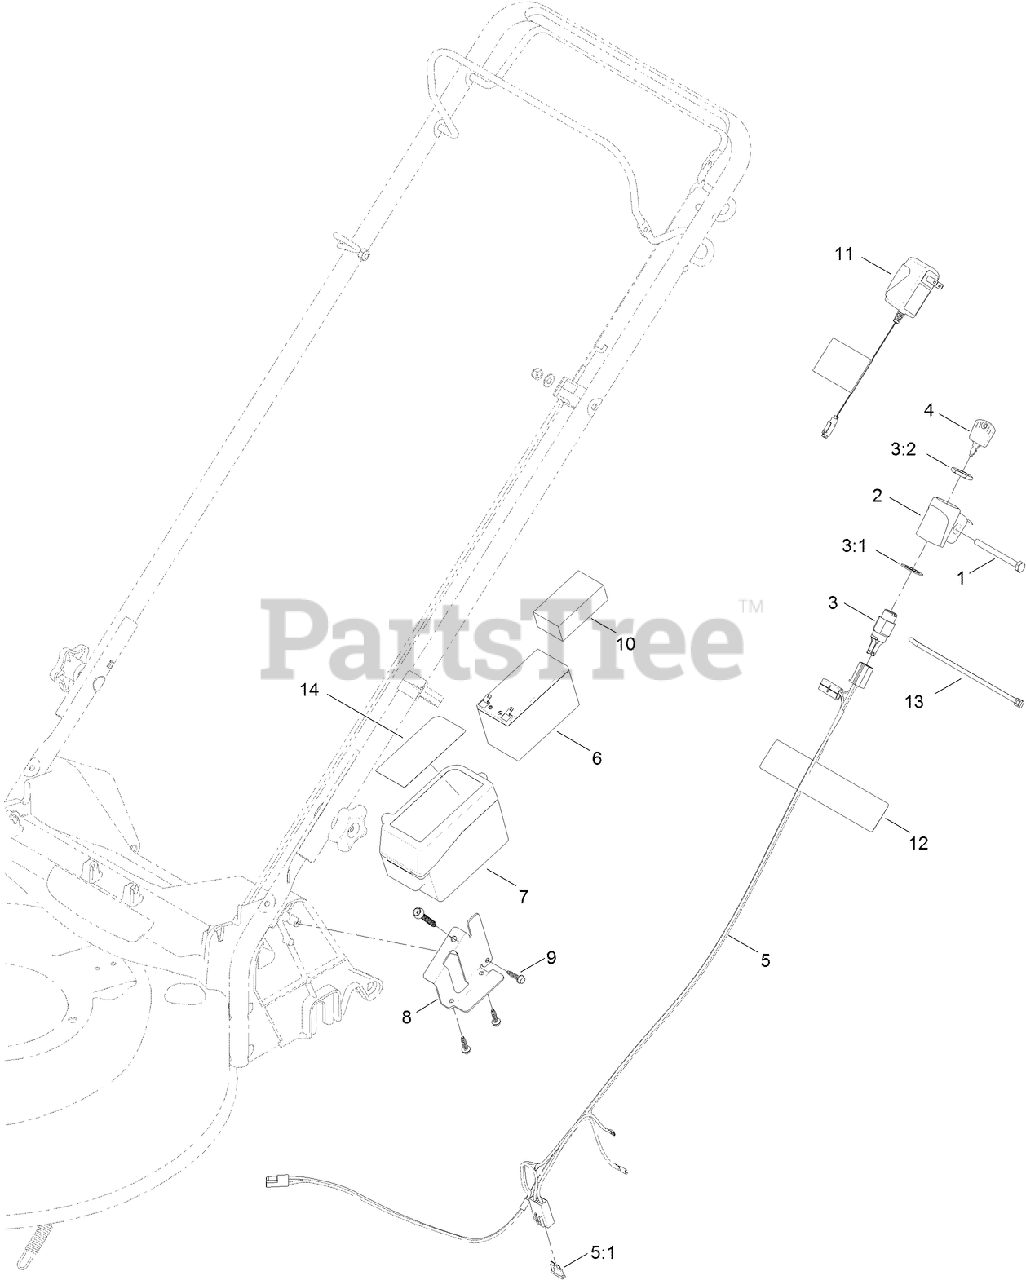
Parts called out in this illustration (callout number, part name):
1	SCREW-HH
2	MOUNT-SWITCH
3	STARTER SWITCH ASM
3:1	WASHER-LOCK
5	HARNESS-WIRE
5:1	FUSE-40 AMP
6	BATTERY-NONSPILLABLE, 12 V
7	BATTERY BOX ASM
8	BRACKET-BATTERY
9	SCREW-HWH
10	FOAM-BATTERY, TOP
12	DECAL-WARNING
13	TIE-CABLE
